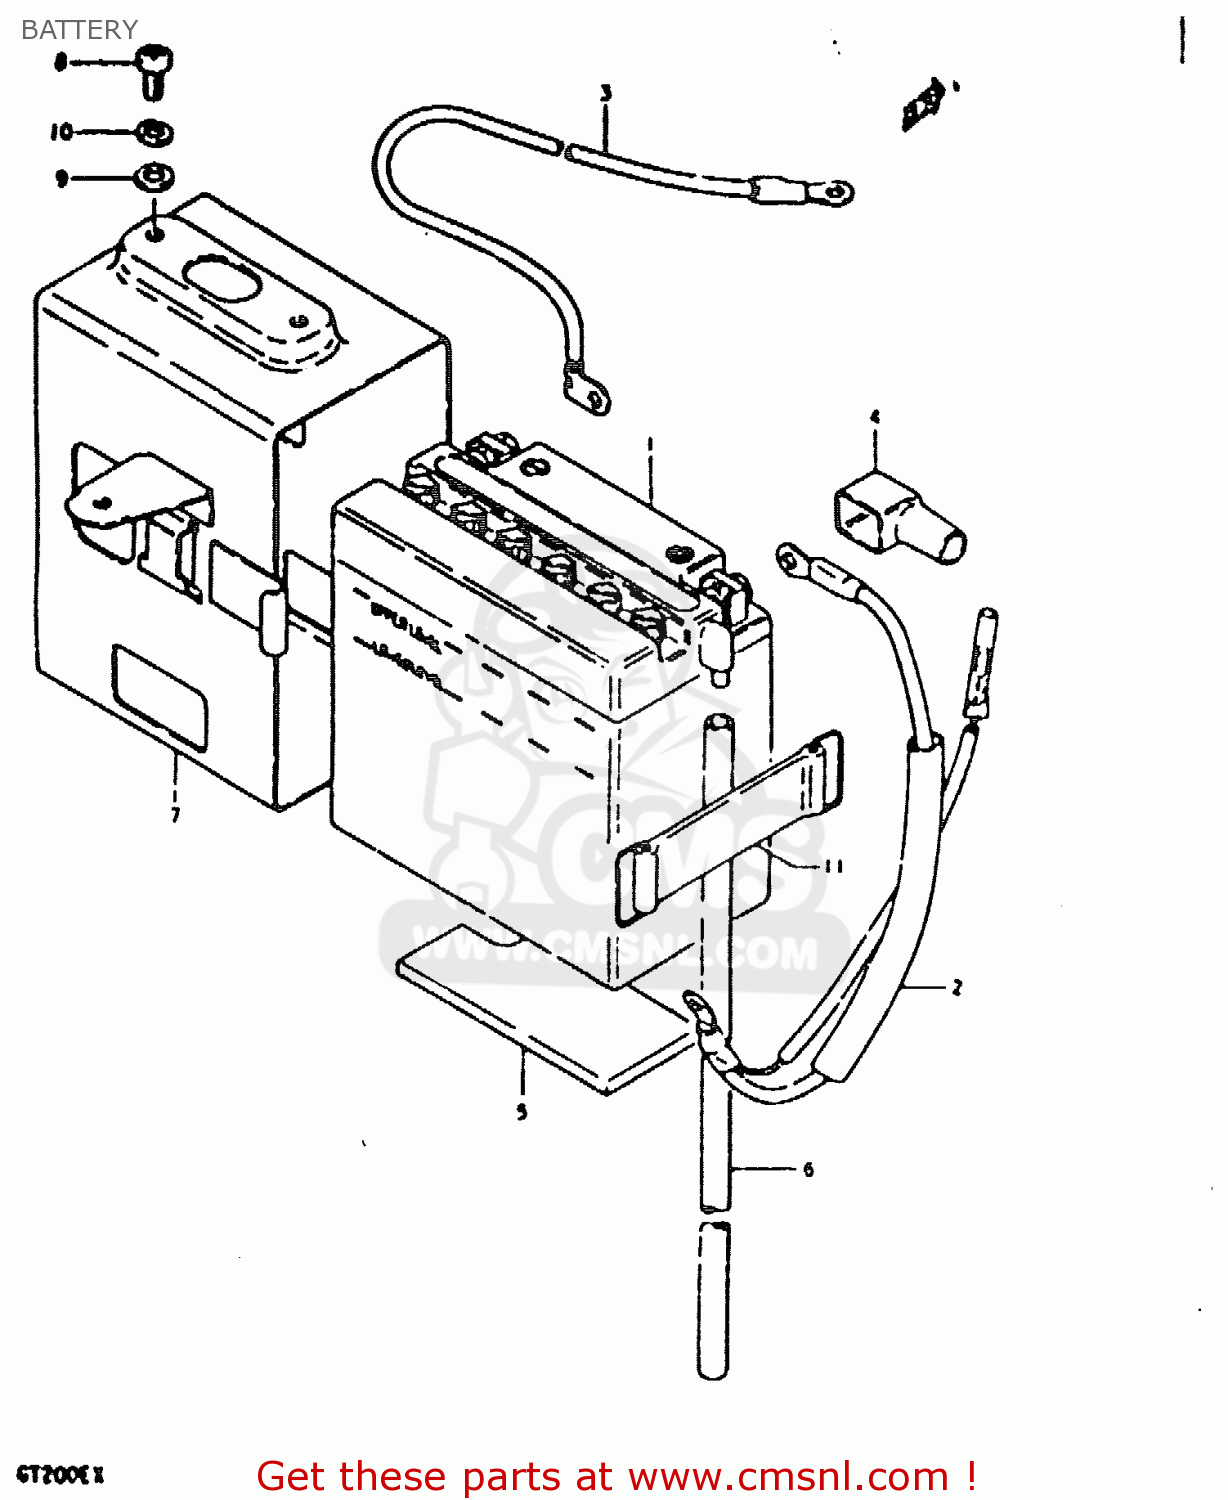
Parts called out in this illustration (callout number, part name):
1	BATTERY ASSY(YB7-A)
2	WIRE,BATTERY PLUS
3	LEAD WIRE, (-)
4	CAP,TERMINAL
5	PROTECTOR,BATTERY
6	HOSE, EXHAUST
7	HOLDER, BATTERY
8	SCREW 6X12
9	WASHER
10	LOCK WASHER
11	BAND
